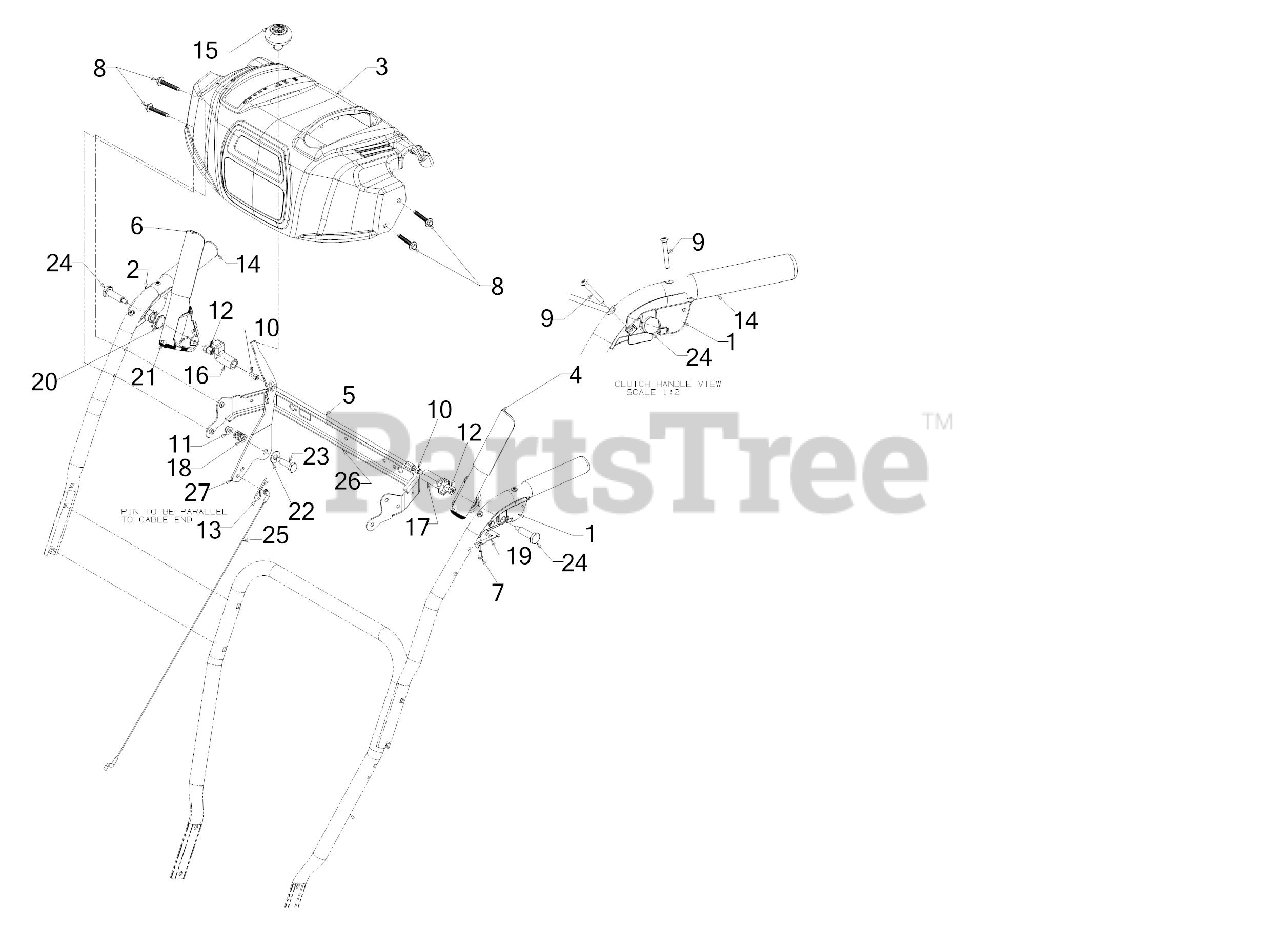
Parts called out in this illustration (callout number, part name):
1	CLUTCH LOCK HANDLE ASSEMBLY (LH)
2	CLUTCH LOCK HANDLE ASSEMBLY (RH)
3	HANDLE PANEL ASSEMBLY (CRAFTSMAN)
4	HANDLE ASSEMBLY (LH)
5	PIVOT ROD
6	ENGAGEMENT HANDLE ASSEMBLY (RH) (RED)
7	SCREW #8-16 x .50
8	SCREW 1/4-20 x 1.625
9	SCREW #10-24 x 1.375
10	SCREW 1/4-20 x .50
11	FLANGE LOCK NUT
12	HEX NUT W/PATCH
13	INTERNAL COTTER PIN
15	SHIFT KNOB
16	LOCK PLATE
17	CLUTCH LOCK CAM
18	COMPRESSION SPRING
19	CLUTCH SPRING
20	TORSION SPRING
21	RUBBER BUMPER
22	FLAT WASHER
23	SHOULDER SCREW
24	SHOULDER SCREW .437 x 1.345 1/4-20
25	SPEED SELECTOR CABLE (PLASTIC)
26	HANDLE SUPPORT BRACKET
27	SHIFT LEVER
